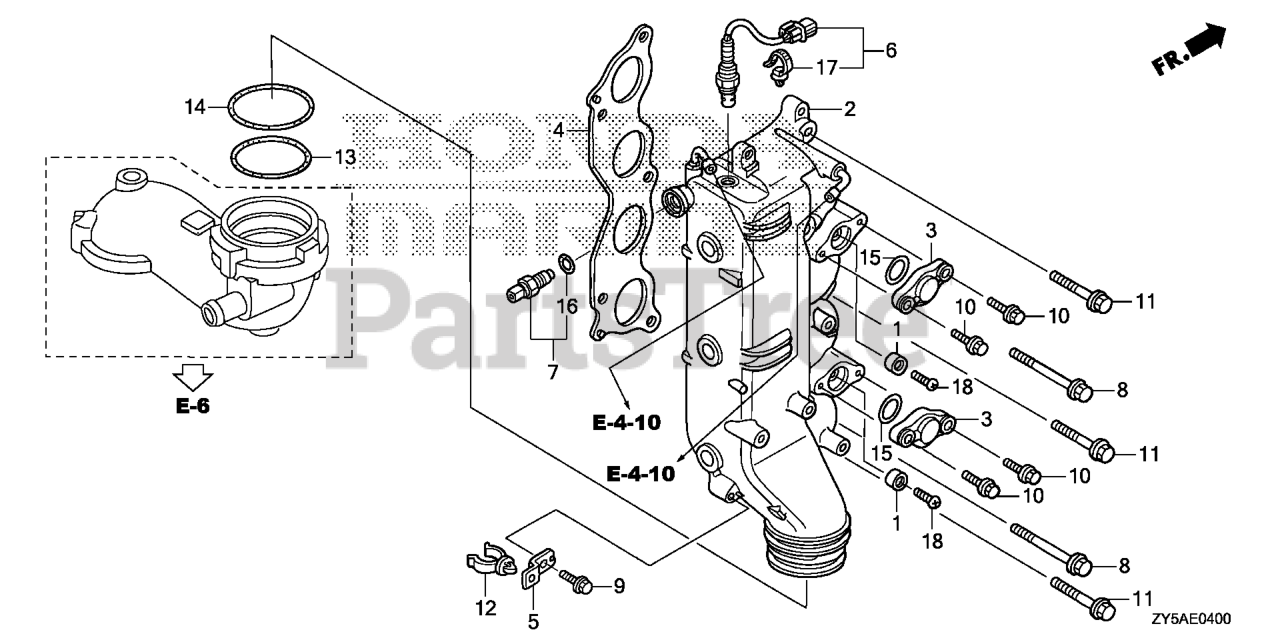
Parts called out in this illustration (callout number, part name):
1	METAL, ANODE
2	MANIFOLD, EX. *NH8* (DARK GRAY)
3	COVER, EX. MANIFOLD *NH8* (DARK GRAY)
4	GASKET, EX. MANIFOLD
5	BRACKET, WATER TUBE CLAMP
6	SENSOR, LAF
7	SENSOR ASSY., WATER TEMPERATURE
8	BOLT, FLANGE (10X75)
9	BOLT, FLANGE (6X14)
10	BOLT, FLANGE (6X22)
11	BOLT, FLANGE (10X45)
12	CLAMP B, WATER TUBE
13	O-RING (76.4X3.1)
14	O-RING (79.8X3.1)
15	O-RING (37X2.4)
16	O-RING (9.5X1.9)
17	CLIP, HARNESS BAND (145.2MM) (NATURAL)
18	BOLT, FLANGE (6X18)
18	SCREW, PAN (6X18)
